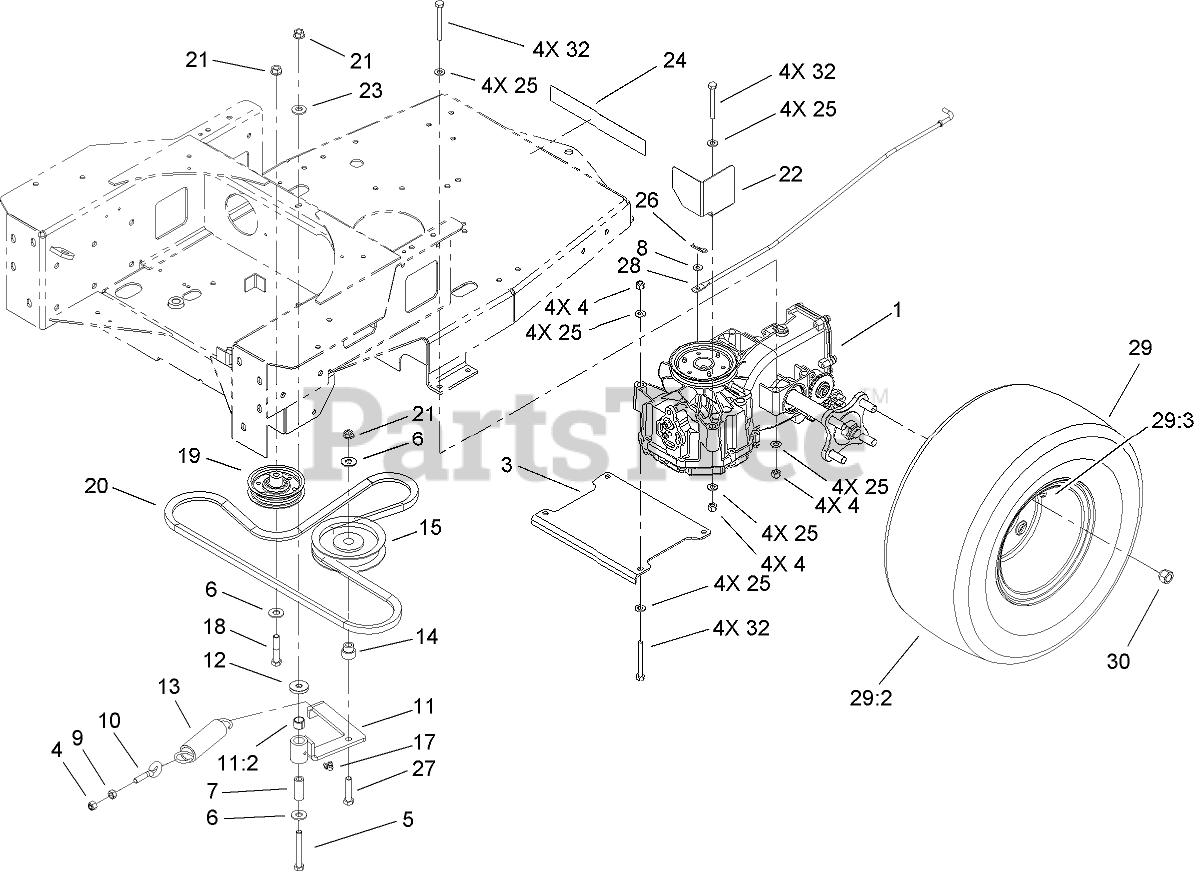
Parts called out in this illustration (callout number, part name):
1	HYDRO-LH
3	PLATE-HYDRO, LOWER
4	NUT-LOCK, NI
5	SCREW-HH
6	WASHER-FLAT
7	BUSHING
8	WASHER-FLAT
9	NUT-HF
10	BOLT-EYE
11	IDLER ARM ASM
11:2	SLEEVE-BEARING
12	SPACER
13	SPRING-EXTENSION
14	BUSHING-IDLER
15	PULLEY-IDLER
17	FITTING-GREASE, 90 DEG
18	SCREW-HH
19	PULLEY-IDLER
20	BELT-V
21	NUT-HF
22	GUARD-FAN, LH
23	WASHER-BELLEVILLE
25	WASHER-PLAIN
26	PIN-COTTER
27	SCREW-HH
28	ROD-LH
29	WHEEL AND TIRE ASM
29:3	STEM-VALVE
30	NUT-LUG
32	SCREW-HH
